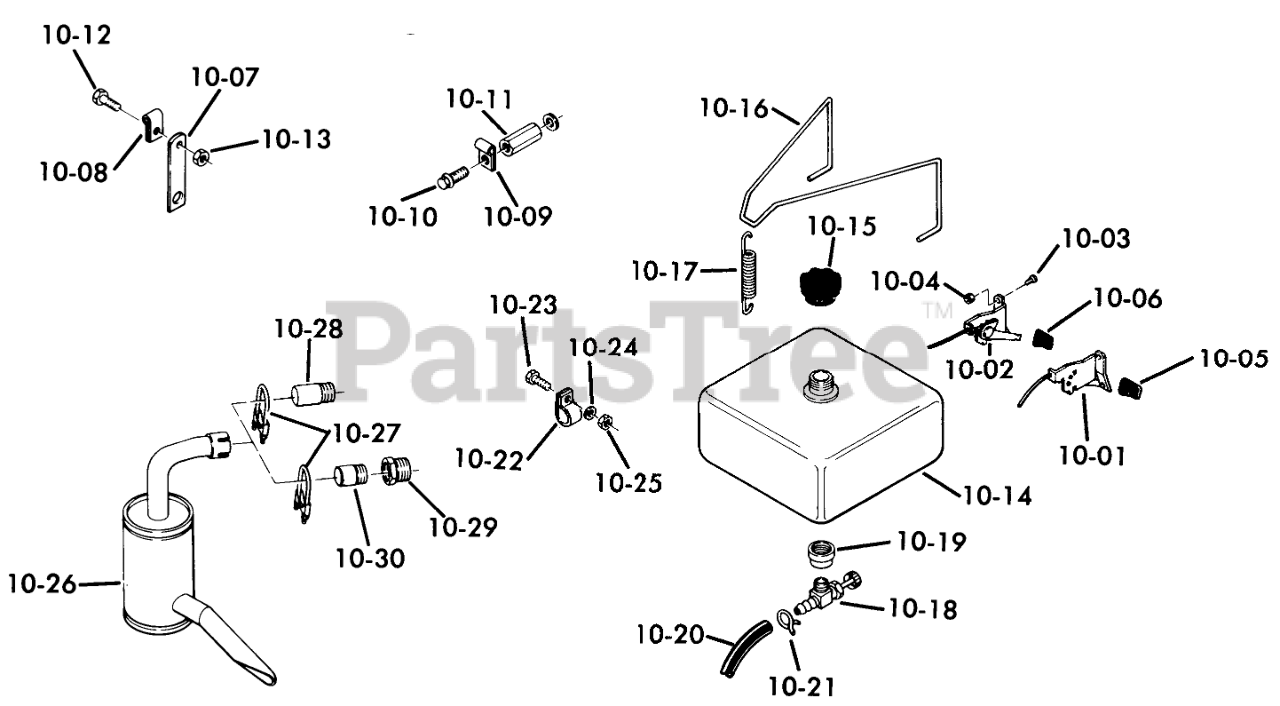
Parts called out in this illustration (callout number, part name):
10-01	Choke Control
10-02	THROTTLE CONTROL
10-03	SCREW
10-04	#10-24 Kep-Nut
10-05	KNOB-CHOKE
10-06	KNOB-THROTTLE
10-07	Strap
10-08	THROTTLE CONTROL CLP
10-09	Clip
10-10	Screw
10-11	Special Nut
10-12	Screw
10-13	Nut
10-14	ASSY-FUEL TANK
10-15	Cap
10-16	HOLD DOWN WIRE
10-17	CLUTCH SPRING
10-18	VALVE-FUEL
10-19	BUSHING
10-20	Fuel Hose
10-21	Clamp
10-22	CLAMP-HOSE
10-23	Bolt
10-24	WASHER 5/16 SAE
10-25	Nut
10-26	Muffler
10-27	ASSY-MUFFLER CLAMP
10-28	NIPPLE
10-29	REDUCER 1 1/4-1
10-30	NIPPLE- 1X2 SPECIAL
